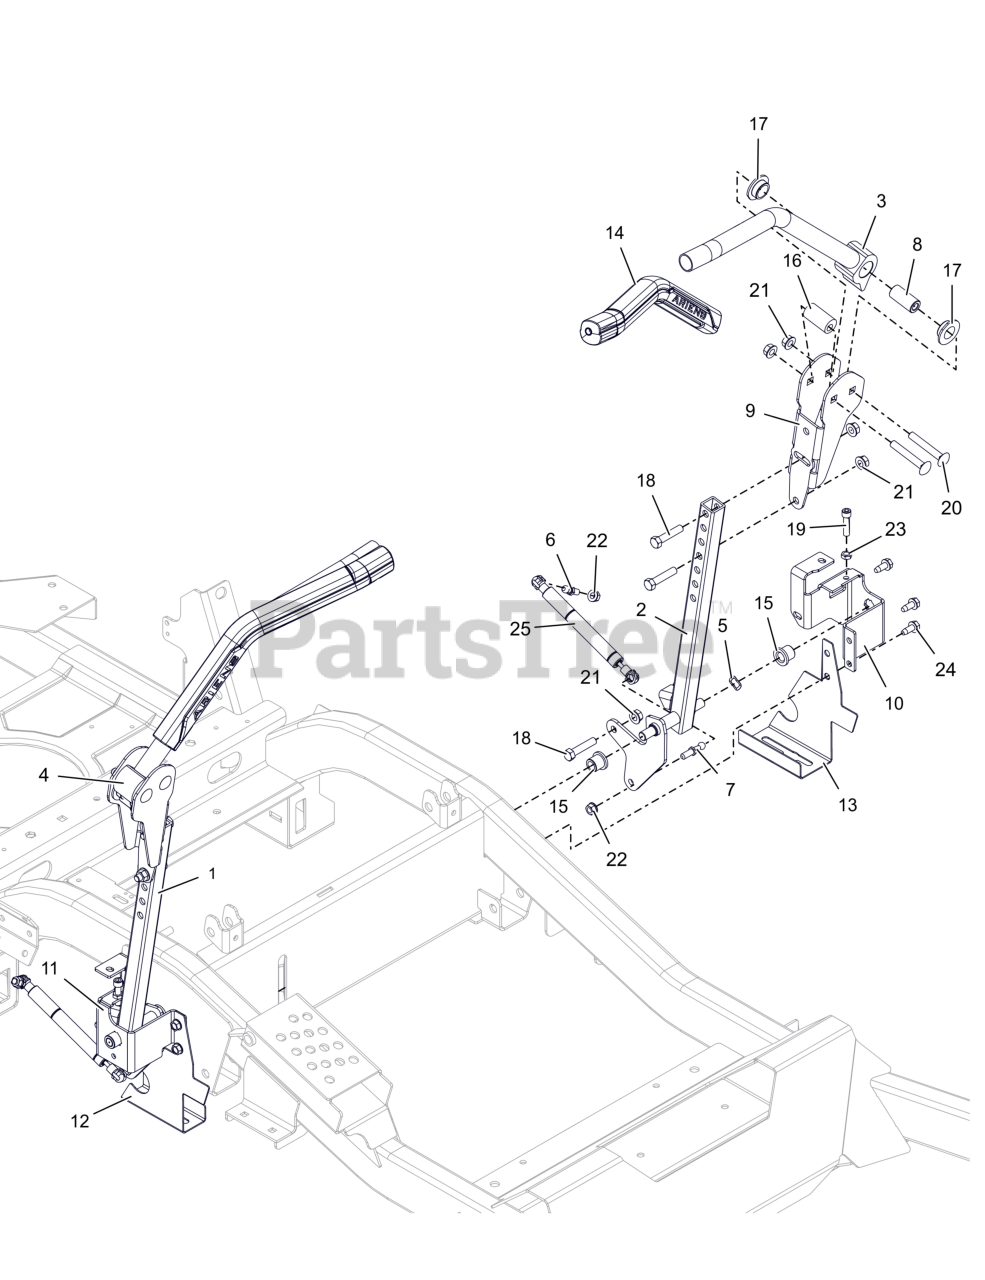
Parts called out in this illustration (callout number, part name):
1	WLDMT, STEERING RH
2	WLDMT, STEERING LH
3	WLDMT, CONTROL HANDLE-LH (BLACK)
4	WLDMT, CONTROL HANDLE-RH (BLACK)
5	WAVE WASHER .531X.781X.125FH
6	STUD- BALL
7	STUD-BALL-THREADED
8	SPACER, STEERING ARM
9	ADJ UPPER CONTROL ARM BRKT-BLK
10	BRKT, STEERING ARM MOUNT -LH
11	BRKT, STEERING ARM MOUNT -RH
12	GUARD, FRAME RAIL BELT RH
13	GUARD, FRAME RAIL BELT LH
14	GRIP- HANDLEBAR ARIENS
15	BHSG-FLG .500X.750X.750X.125
16	BSHG, ECCENTRIC.406X.875X1.625
17	BSHG-FLG .762X1.48X.44 IGLIDER
18	BLT, HEX .38-16X1.75 G5 ZCC
19	BLT, SHCS .312-18X1.25 G8 SS
20	BLT, RHSSN.38-16X2.50 G5 ZCC
21	NUT-LK-TOP-FLG .38-16 ZC120
22	NUT,LK-CTR-FLG .31-18 GF ZCC
23	NUT-JAM .312-18 G2 ZCC
24	SCR,TAP .312-18X.75 HWH TR ZCC
